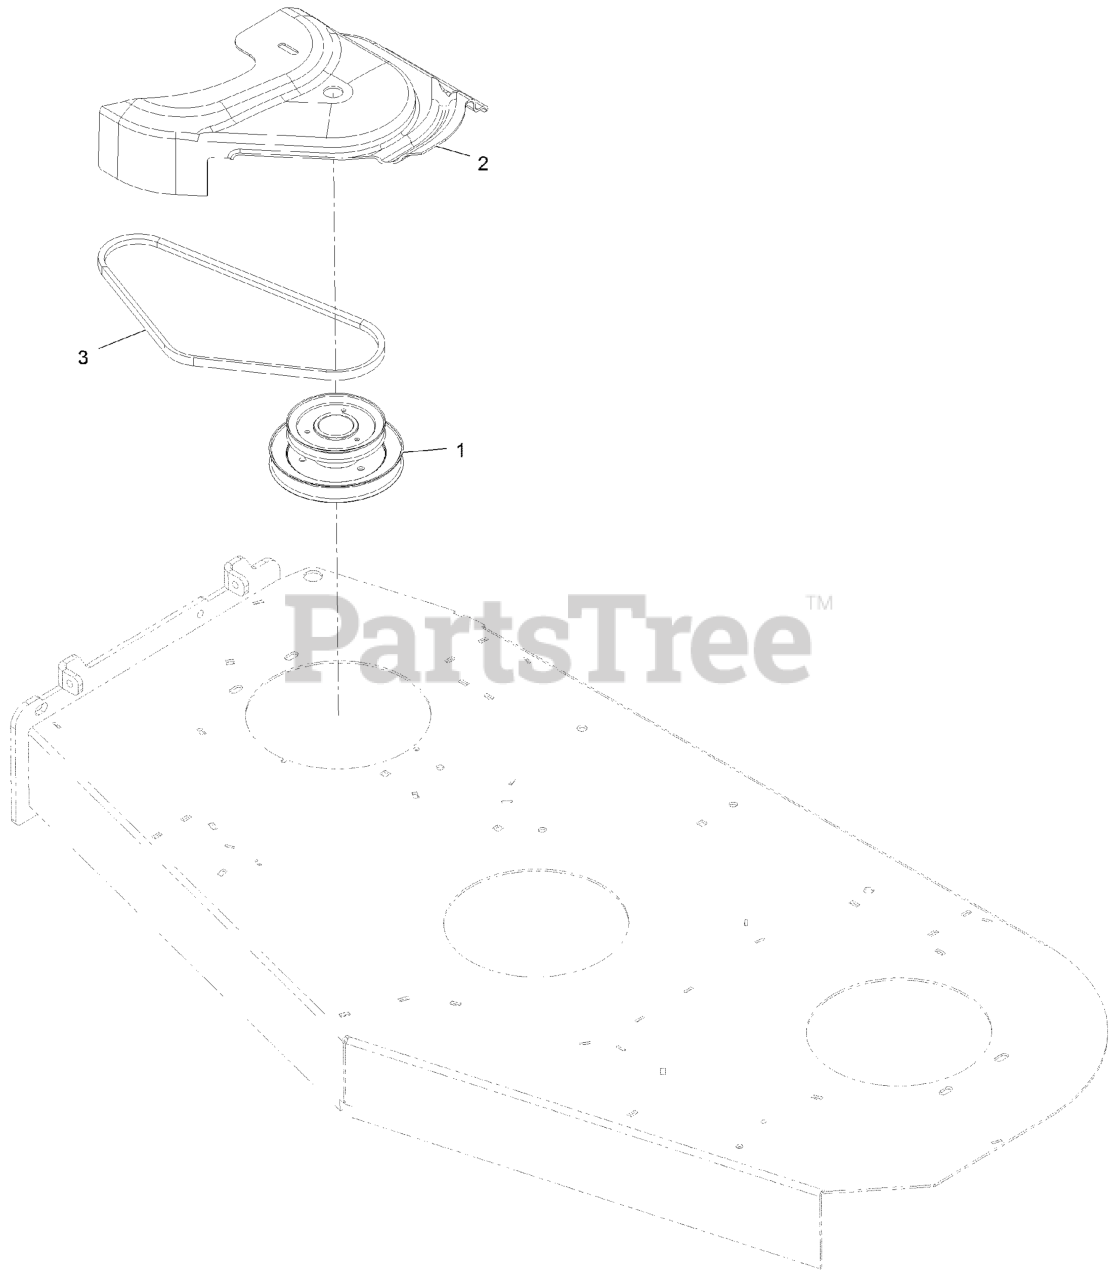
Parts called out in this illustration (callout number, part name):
1	JACKSHAFT, UV DRIVE 604 S
2	COVER,BELT DUV 60
3	BELT, BLOWER DRIVE 60
